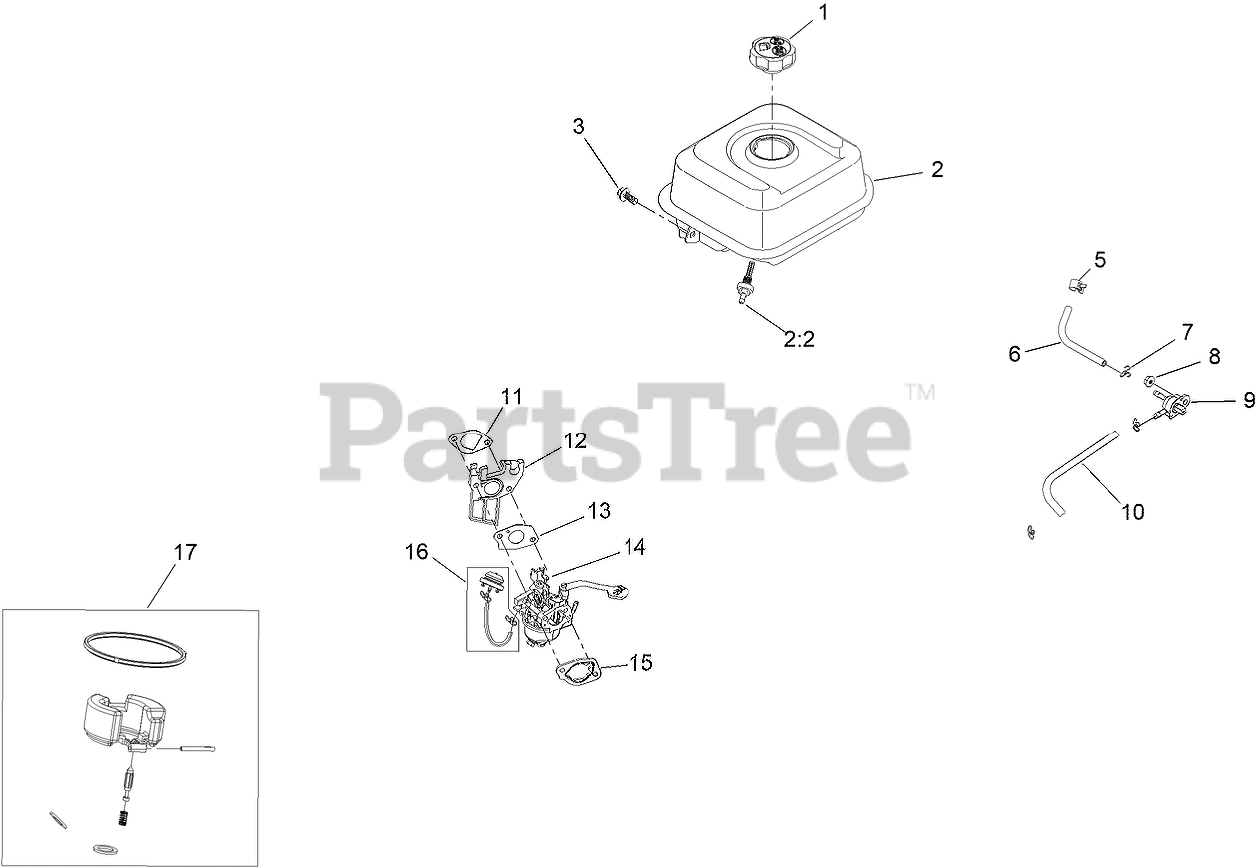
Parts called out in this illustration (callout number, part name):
1	CAP-FUEL
2	FUEL TANK AND FILTER ASM
2:2	FILTER-FUEL
3	SCREW-HHF
5	CLAMP-HOSE
6	HOSE-FUEL, FORMED
7	CLAMP-HOSE
8	NUT-FLANGE
9	VALVE-FUEL
10	HOSE-FUEL, FORMED
11	GASKET-CARBURETOR
12	INSULATOR-CARBURETOR
13	GASKET-CARBURETOR
14	CARBURETOR ASM
15	GASKET-CARBURETOR
16	PRIMER KIT
17	INTERNAL CARB SERVICE KIT
